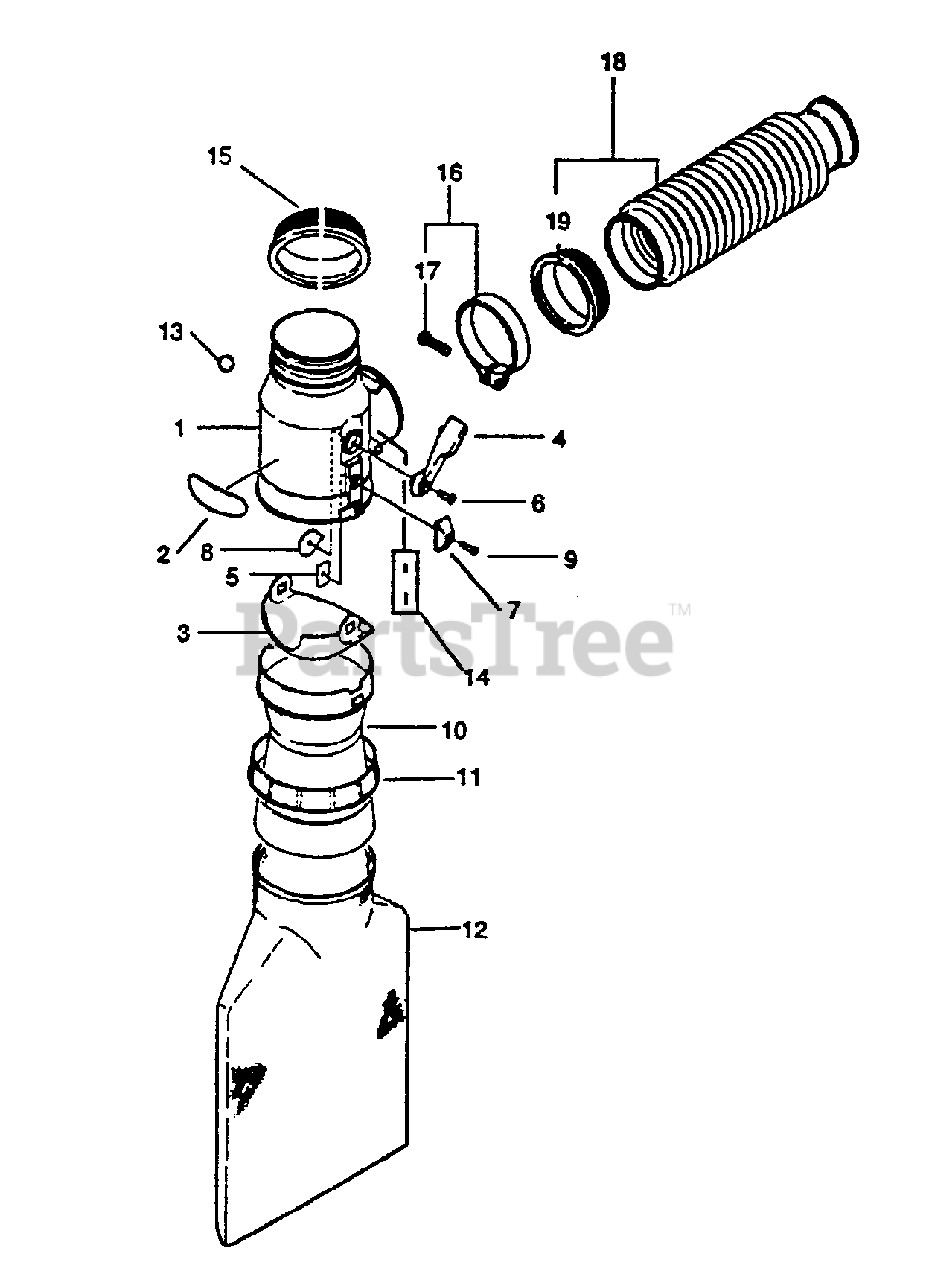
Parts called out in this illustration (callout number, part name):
1	TUBE, SUCTION
2	LABEL - ECHO
6	SCREW 5×14
9	SCREW 4×14
10	CONNECTOR
12	BAG, VACUUM
13	RING, RETAINING - 8
15	COUPLER, SUCTION
16	CLAMP KIT
17	SCREW 5×20
18	FLEXIBLE TUBE KIT
19	COLLAR
